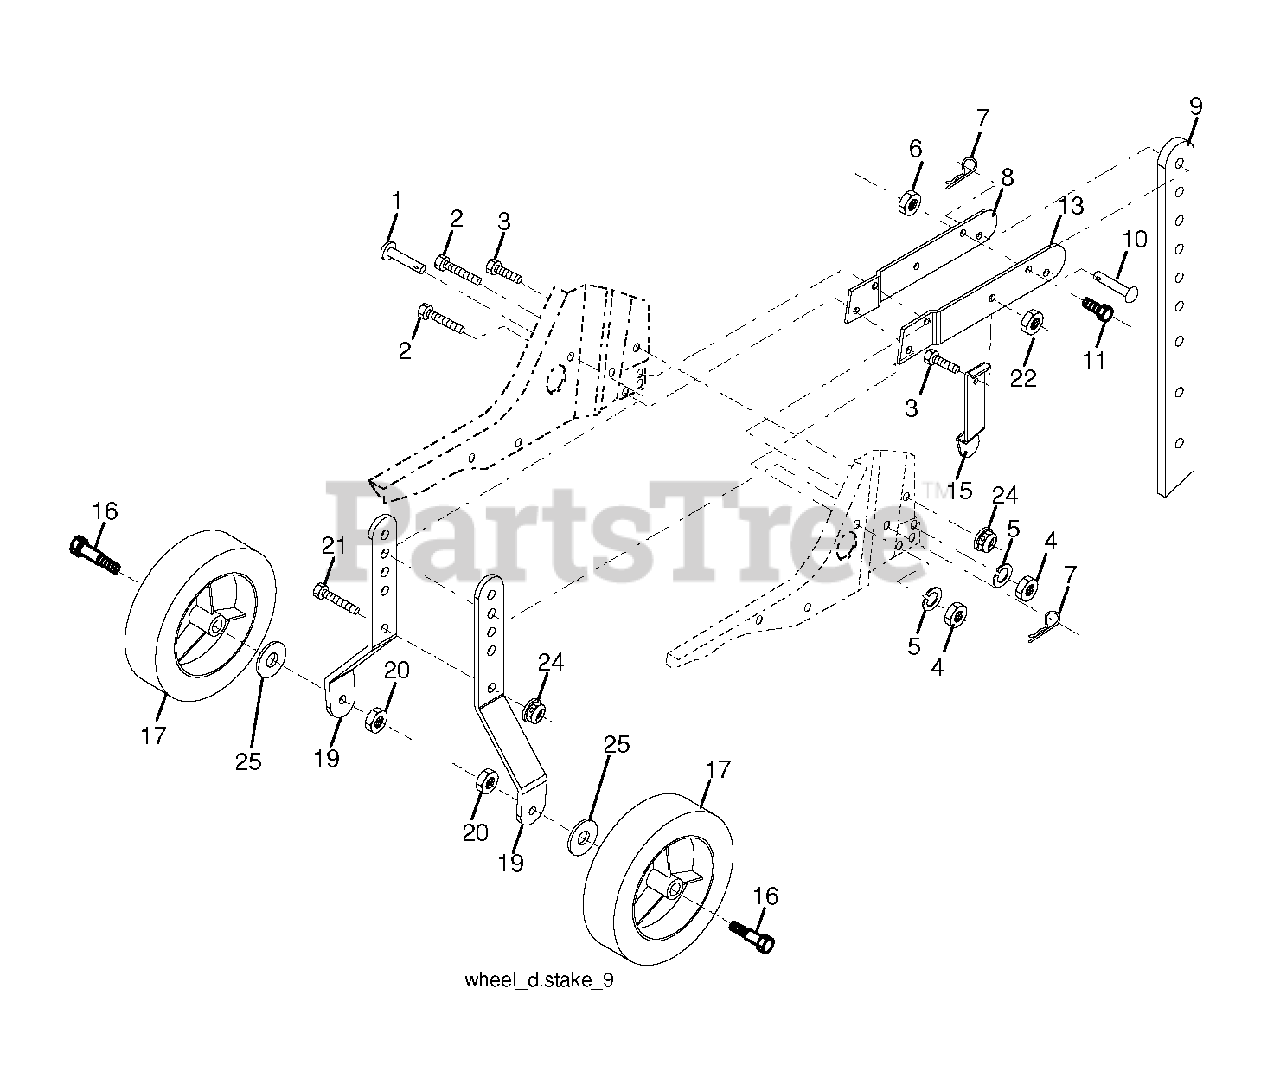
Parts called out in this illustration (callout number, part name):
1	PIN
2	BOLT
3	BOLT
5	LOCKWASHER
6	NUT
9	RP STAKE.DEPTH.13.25.W/9HOLES
11	Bolt
15	RP SPRING
16	BOLT.SHOULDER
17	WHEEL.8X1.75.MAG.CLOSE.BLACK
19	RP.BRACKET.WHEEL.BLACK
20	LOCKNUT
22	NUT.71038.31-18.HEX.NYLOCK
24	LOCKNUT-FLANGE 5/16-18
